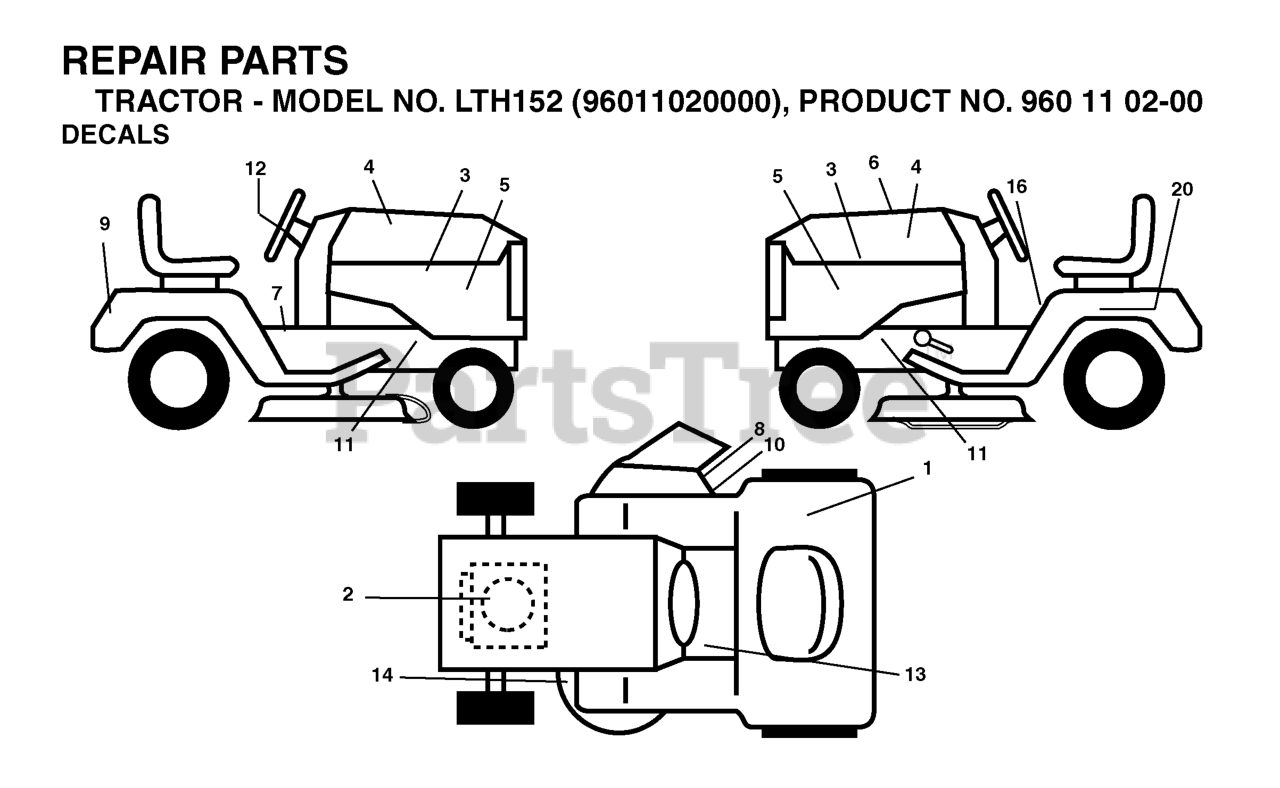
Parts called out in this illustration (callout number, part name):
1	Decal, Fender 100 DB/CE
2	DECAL
3	DECAL.HOOD.HUSQVARNA.INTERNATI
7	DECAL PARK BRAKE
8	DECAL.INTERNATIONL.CUTFINGER
10	DECAL, DEFLECT WARNING
12	DECAL.STEERING.HUSQ.BLUE
13	DECAL
14	DECAL V BELT SCHEMATIC
16	LABEL
20	DECAL BTRY SYMBOLS
